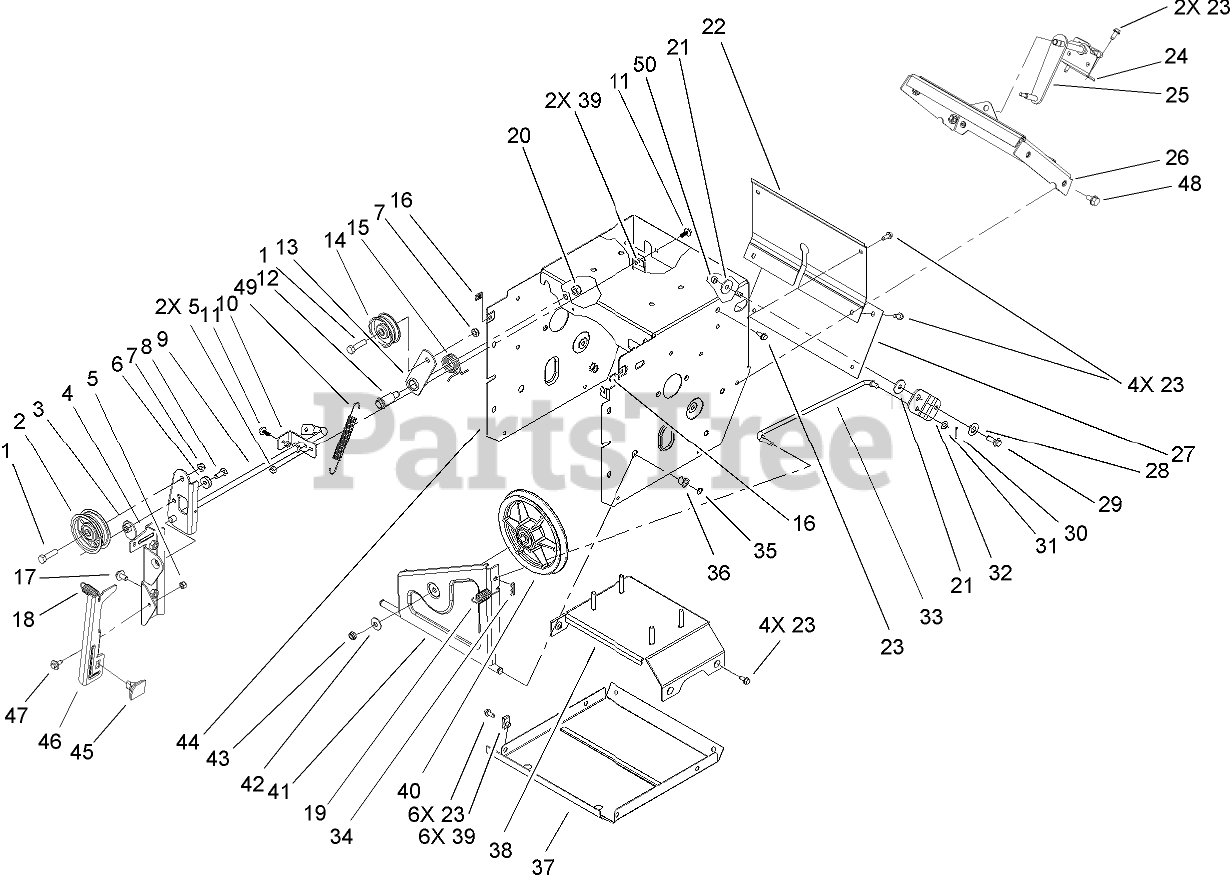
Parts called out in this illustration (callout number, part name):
1	SCREW-HH
2	PULLEY-IDLER
4	BRACKET-IDLER, IMPELLER
5	NUT-LOCK, NI
6	WASHER-BELLEVILLE
7	NUT-LOCK, NI
8	SCREW-HH
9	AUGER CLUTCH ASM
10	BRACKET-REAR, CLUTCH
11	SCREW-HHF
12	BOLT-SHOULDER
13	ARM-IDLER, TRACTION
14	PULLEY-IDLER
15	SPRING-TORSION, RH
16	NUT-SPEED, U-TYPE
17	SCREW-HHF
18	SPRING-EXTENSION
19	SPRING-EXTENSION
20	NUT-LOCK, NI
21	WASHER-PIVOT
22	COVER-UPPER
23	SCREW-HWH
24	BRACKET-SHIFT ROD
25	LEVER-CONTROL, TRACTION
26	SHIFT PLATE ASM
27	COVER-LOWER
28	WASHER
29	SCREW-SHOULDER
30	PIN-COTTER
31	WASHER-PLAIN
32	BELLCRANK-DRIVE
33	LINK-CONTROL, SPEED
34	PIN-COTTER
35	RING-RETAINING
36	BUSHING-NYLINER
37	PAN-BOTTOM
38	BRACE FRAME ASM
40	PULLEY-TRACTION
41	PULLEY PIVOT ASM
42	WASHER-BELLEVILLE
43	NUT-HEX
44	FRAME-TRACTION
45	PAD-BRAKE
46	ARM-BRAKE
47	SCREW-SHOULDER
48	SCREW-HWHTF
49	SPRING-EXTENSION
50	NUT-LOCK, NI
